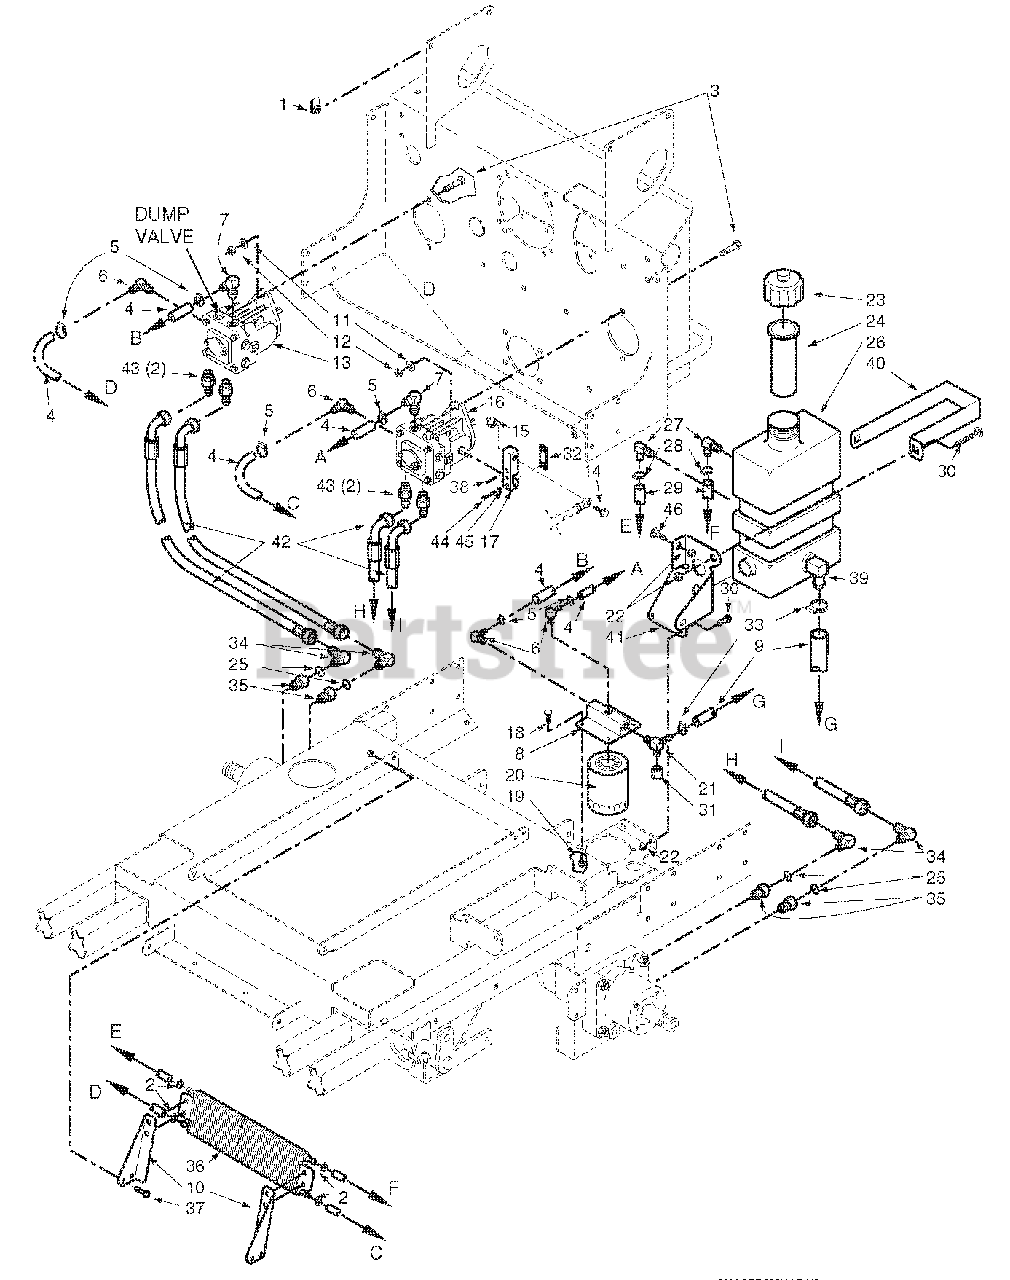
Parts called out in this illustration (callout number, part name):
1	U-Nut 1/4-20
2	Hose Clamp, 0.69" Dia.
3	Bolt, Hex Head 1/4-20 x 2.0"
4	Hose, 3/8" ID Pushlock -
5	Clamp, Hose 1/2"
6	Elbow, 90 Degree - 9/16" O-Ring x 3/8" Hose
7	Elbow, 90 Degree - 3/4" O-Ring x 3/8" Hose
8	Oil Filter Base
9	Hose Assembly, 1/2" ID (Tank to Filter Base)
10	Mounting Bracket - LH, Oil Cooler
10	Mounting Bracket - RH, Oil Cooler
11	Flatwasher, 3/8" (.391 x .938 x .105")
12	Nut, Hex Elastic Stop 3/8-16
13	Pump, Right Hand
14	Bolt, Hex Head, 3/8-16 x 1-1/4"
15	Nut, Hex, Elastic Stop 3/8-16
16	Pump, Left Hand
17	Block, Pump Control
18	Bolt, Hex Head 5/16-18 x 1.0" Zinc
19	Nut, Serrated Flange 5/16-18
20	Oil Filter
21	Tee, 3/4" O-Ring x JIC x 1/2" Hose
22	Nut, Hex Elastic Stop 1/4-20
23	Cap, Hydraulic Tank
24	Insert, Filler Neck
25	O-Ring
26	Oil Reservoir Assembly
27	Elbow, 90 Degree .38" Hose
27	Bushing, .56" Dia. Viton
28	Hose Clamp, 0.69" Dia.
29	Hose, 3/8" ID, Pushlock
30	Screw, Phillips Head, 1/4-20 x 2"
32	Clamp Plate, Pump Control
33	Clamp, Hose
34	Elbow, 90 Degree, 1/2" x 1/2"
35	Bushing, 7/8"-14 JIC x 3/4"-16 O-Ring
36	Cooler, Oil
37	Bolt, Hex Head 5/16-18 x 3/4"
38	Roll Pin, Spring 3/16 x 3/4"
39	Elbow, 90 Degree
39	Bushing, .78" Dia. Viton
40	Strap, Hydraulic Tank
41	Support Bracket, Hydraulic Tank
42	Hose Assembly, Pump
43	Union, 3/4"-16 JIC x 3/4"-16 O-Ring
44	Bolt, Hex Head, 1/4-20 x 1-1/4"
45	Lockwasher, 1/4" Spring
46	Bolt, Hex Head 1/4-20 x 3/4"
